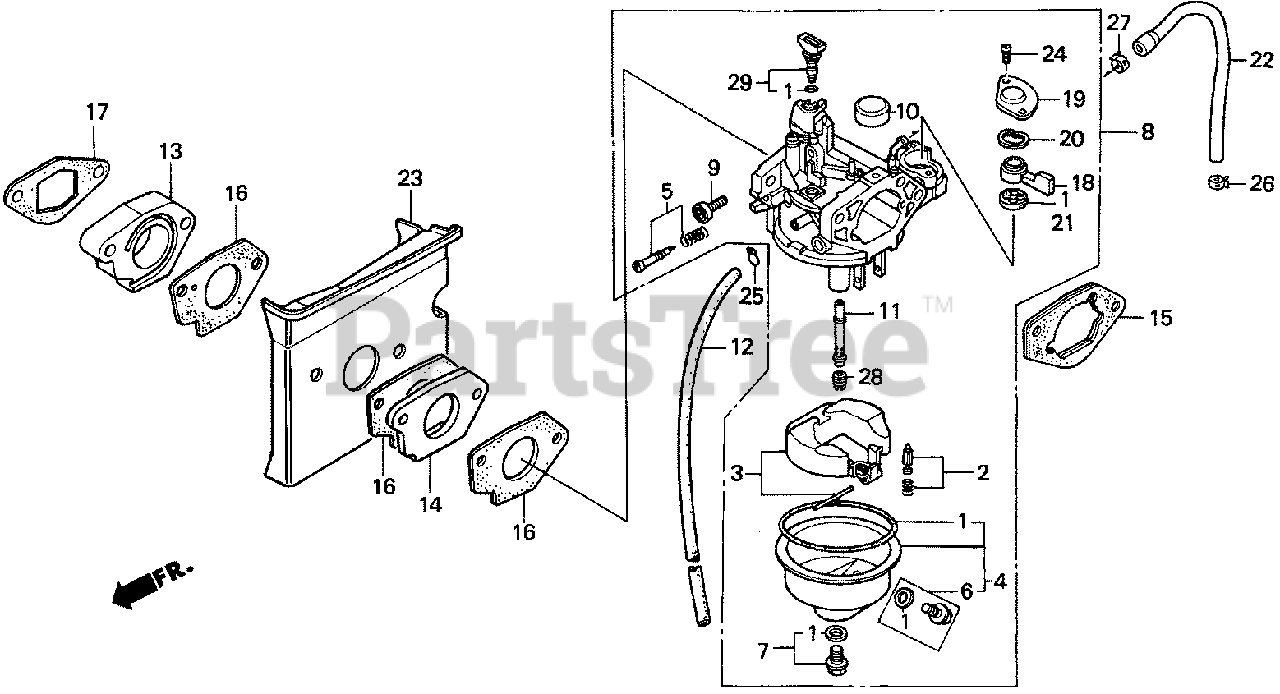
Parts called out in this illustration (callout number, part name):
1	GASKET SET
1	GASKET SET (EXCEPT 16173-001-004)
2	VALVE SET, FLOAT
4	CHAMBER SET, FLOAT
5	SCREW SET, PILOT
6	SCREW SET, DRAIN
7	SCREW SET
8	CARBURETOR ASSY. (BB36A B)
8	CARBURETOR ASSY. (BB36A C)
9	SCREW, THROTTLE STOP
10	CAP, CHOKE DUST
11	NOZZLE, MAIN
12	TUBE, AIR VENT
13	INSULATOR, CARBURETOR
14	INSULATOR, CARBURETOR
15	SPACER, CARBURETOR
16	GASKET, CARBURETOR
17	GASKET, INSULATOR
18	LEVER, PETCOCK
19	PLATE, LEVER SETTING
20	SPRING, PETCOCK LEVER
21	GASKET, PETCOCK
22	TUBE, FUEL
23	GUIDE, AIR
24	SCREW, PAN (3X6)
24	SCREW, PAN (3X8)
25	CLIP, TUBE (B8)
26	CLAMP, TUBE (D8)
27	CLAMP, TUBE (D10)
28	JET, MAIN (#82)
28	JET, MAIN (#85)
28	JET, MAIN (#88)
29	JET SET, PILOT (#40)
